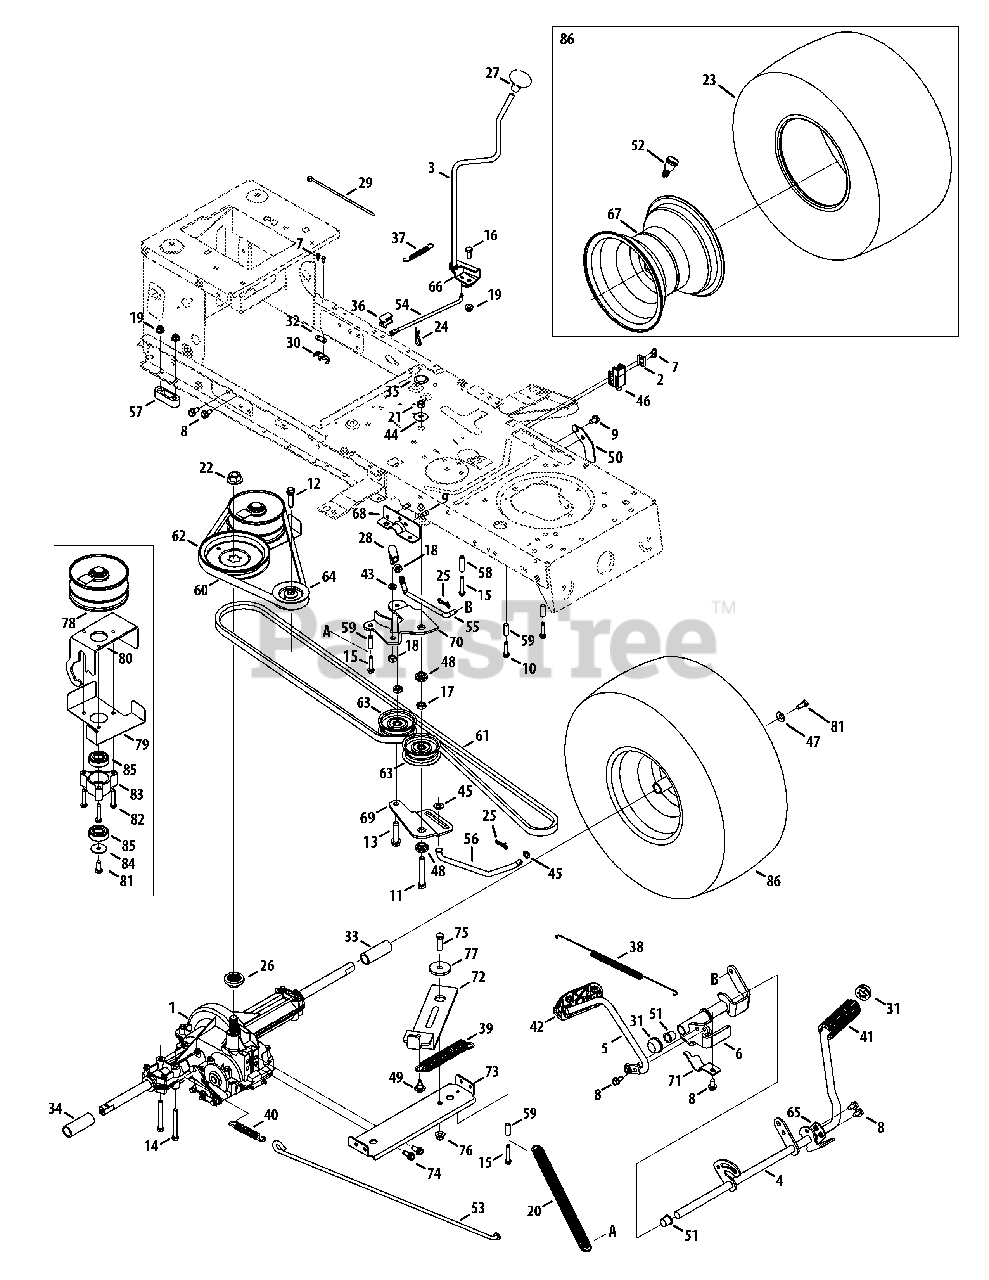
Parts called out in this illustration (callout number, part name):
1	Drive Assembly, autodrive
2	Plate Switch
3	Lever Asm, Shaft
4	Pedal Asm, drive, autodrive
5	Pedal Asm, cont, autodrive
6	Bracket Asm, pedal, autodrive
7	Screw, ab, #8-18, 0.500, Hxindwsh
8	Screw, tt, 5/16-18, .750, Hxindwsh
9	Screw, tt, 5/16-18, .0625, Hxindwsh
10	Screw, tt, 1/4-20, 1.250, Hxindwsh
11	Screw, 3/8-16, 2.50, Gr5, Std
12	Screw, ttsems, 3/8-16, 1.500, Hxlwsh
13	Screw, tt, 3/8-16, 1.750, hxindwsh
14	Screw, 5/16-18, Gr5, Std
15	Screw, tt, 1/4-20, 1.625, Hxindwsh
16	Screw, 5/16-18, .75, Gr5, Std
17	Nut, jam, 7/16-20, Gr2
18	Nut, hex, 3/8-24, Gr5
19	Nut, flglk, 5/16-18, Grf, nylon
20	Spring, extn, .56 x 12.05
21	Nut, hexlck, 3/8-16, Centerlock
22	Nut, flg, 9/16-18, Gr2
23	Tire, 20 X 8 X 8 Sq Shoulder
24	Pin, cotter Int- .125 Dia
25	Pin, cot, bow-Tie
26	Hub, Pulley, 5/8 Spline
27	Knob, Shaft
28	Ball, joint
29	Cable, tie, 3/16
30	Switch, Spring, short
31	Cap, push 5/8
32	Plate, Insulator Nut
33	Slev, 58 X..821 X 3.3125
34	Slev, 758 X .821 X 2.4375
35	Plug, deck Hole, 7/8
36	Bearing
37	Spring, ext, .38 Od X 3.25 Lg
38	Spring, extn, .70 Dia X 12.00 Lg
39	Spring, extn, .97 Od X 6.18 Lg
40	Spring, extn, .59 Od X 4.00 Lg
41	Pad, foot, 4.0 Long
42	Pad, cont
43	Washer, lock, 3/8, Regular Duty
44	Washer, Flat, .406 x 1.920 x .060
45	Washer, flat, .375 X .738 X .063
46	Switch Interlock
47	Bell Washer, .340 x .872 x .060
48	Spacer, shldr, 1.00 X .38 X .38
49	Screw, shldr, .43x.29, Tt, 5/16-18
51	Bearing, flg, .630 Idx .695 Od X .60
52	Valve, tubeless Air
53	Rod, brake, lt-5 Trans
54	Rod, shift, lt-5 Stretch 46"
55	Rod, adj, Idler, 3/8
56	Rod, trans, footpedal Bypass
57	Spacer, T-Axle 68
58	Spacer, .260 X .372 X 1.420 Lg
59	Spacer, .260 X .375 X 1.030 Lg
60	Belt, V-Type, 5l X 40.9 Lg Poly
61	Belt, V-Type, 5l, 90.93, Poly
62	Pulley, V-Type, 7.25 Dia Spun
63	Pulley, Idler, flat
64	Pulley, Idler
65	Bracket, ped, support
66	Bracket, Shaft, adj
68	Bracket, ped, frame Rh
69	Bracket, Idler, center Dbl
70	Bracket, Idler, dbl Autodrive
71	Bracket, supt, pedal Stap
72	Bracket Asm, Idler
73	Bracket Asm, autodrive
74	Screw, tt, 5/16-18, 0.750, Hxindwsh
75	Screw, 3/8-16, 1.25, Gr5, Std
76	Nut, flglk, 3/8-16, Grf, nylon
77	Spacer, shldr, .8840 X .190
78	Pulley Asm, var Speed
79	Keepr Asm, belt
80	Bracket Asm, Variable
81	Screw, 5/16-24, .750, Gr5, Lock
82	Screw, tt, 1/4-20, 1.500, Hxindwsh
83	Cup, Bearing
84	Washer, flat, .330 X 1.25 X .06
85	Bearing, ball
86	Wheel, 20 x 8 x 8
